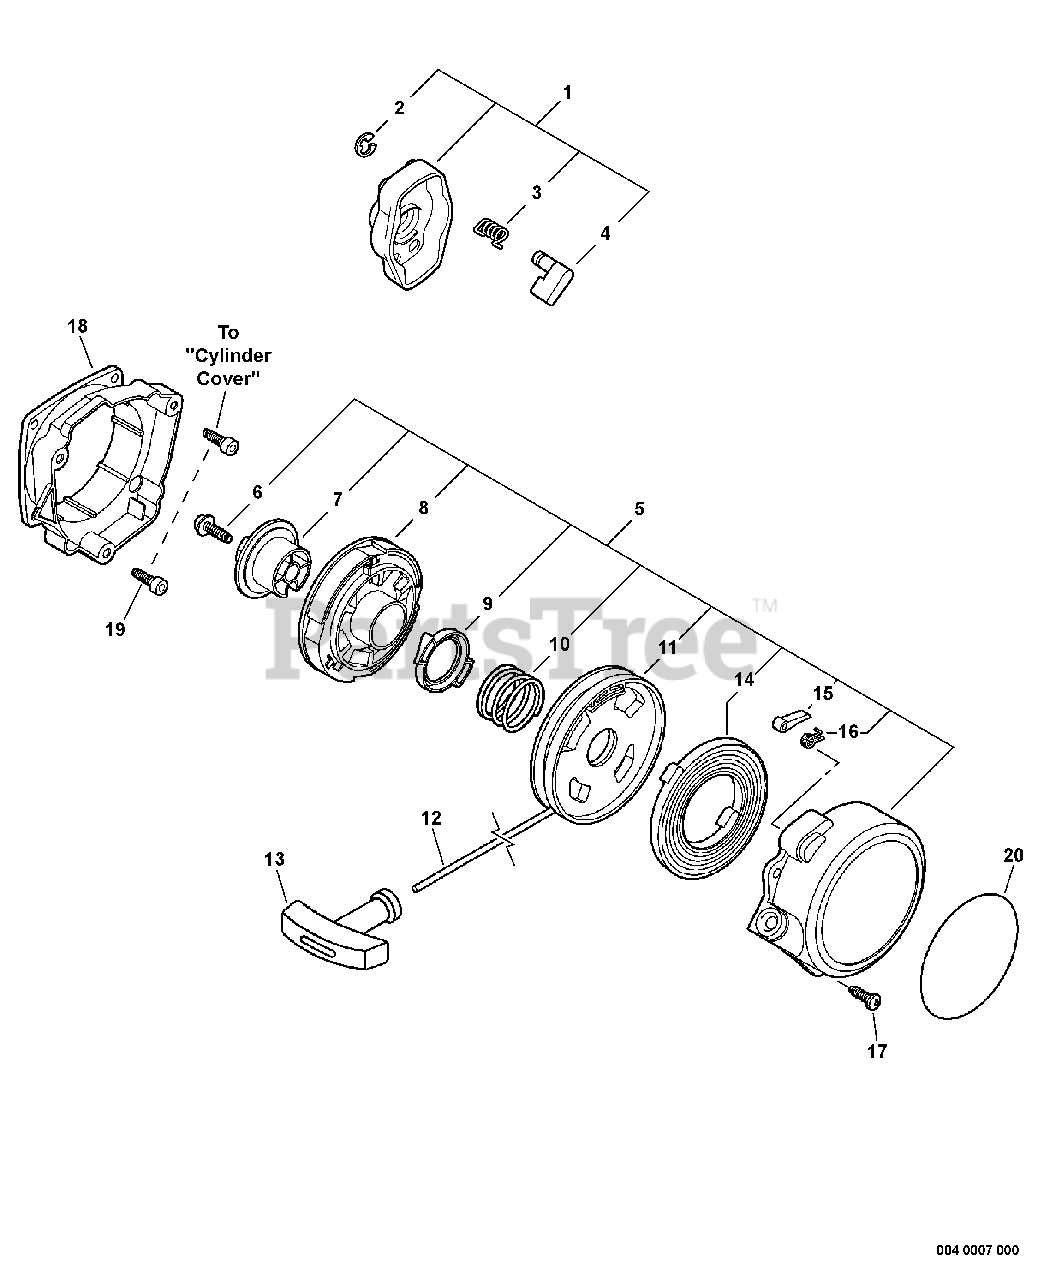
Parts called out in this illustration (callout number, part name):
1	STARTER PAWL ASSY
2	E-RING 4
3	SPRING, RETURN
4	PAWL, STARTER
5	STARTER ASSY
7	PLATE, CAM
8	SPRING ASSY
9	PAWL, STARTER
10	SPRING, RETURN
11	PULLEY, STARTER
12	ROPE, STARTER
13	GRIP, STARTER
14	SPRING, RECOIL
15	PAWL, STARTER
17	SCREW, TAPPING 5×20
19	BOLT 4×16
